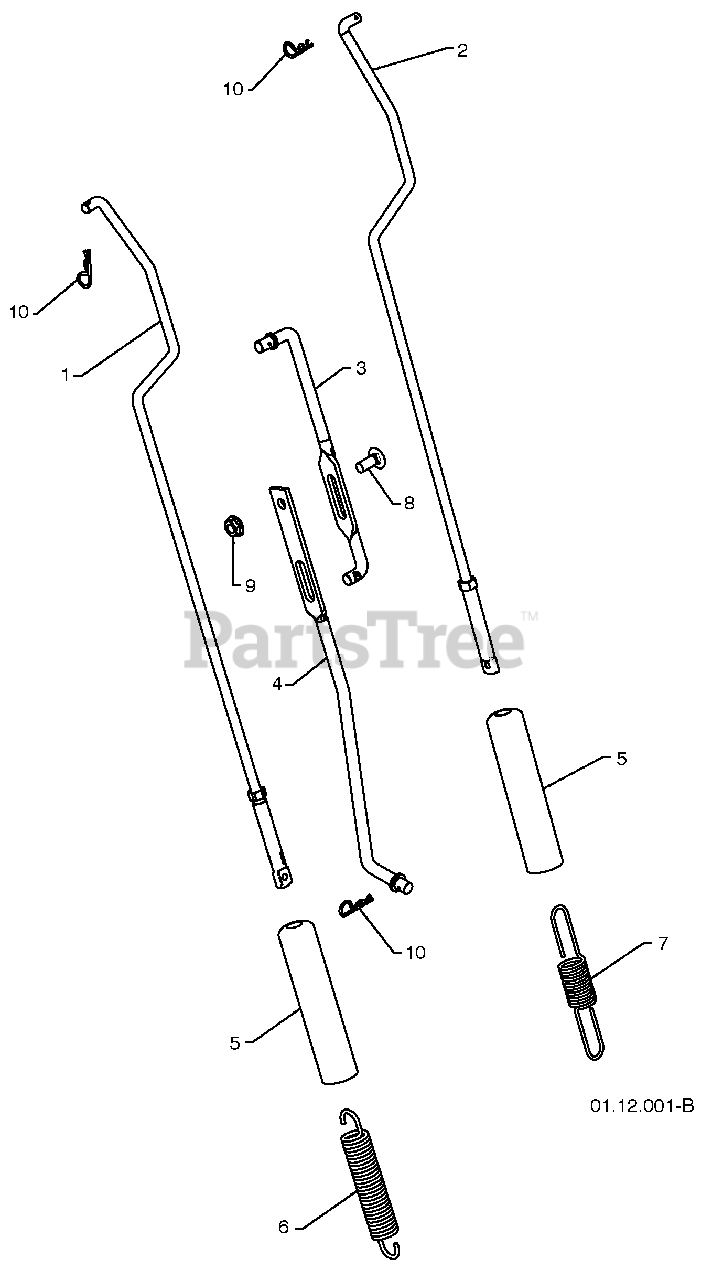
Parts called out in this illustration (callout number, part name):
1	IMPELLER ROD ASSEMBLY
2	TRACTION ROD ASSEMBLY
3	SHIFTER ROD TOP
4	SHIFTER ROD BOTTOM
5	SPRING SLEEVE
6	IMPELLER SPRING
7	TRACTION SPRING
8	CARRIAGE BOLT 5/16-18 X .75
9	NUT 5/16-18
10	RETAINER
